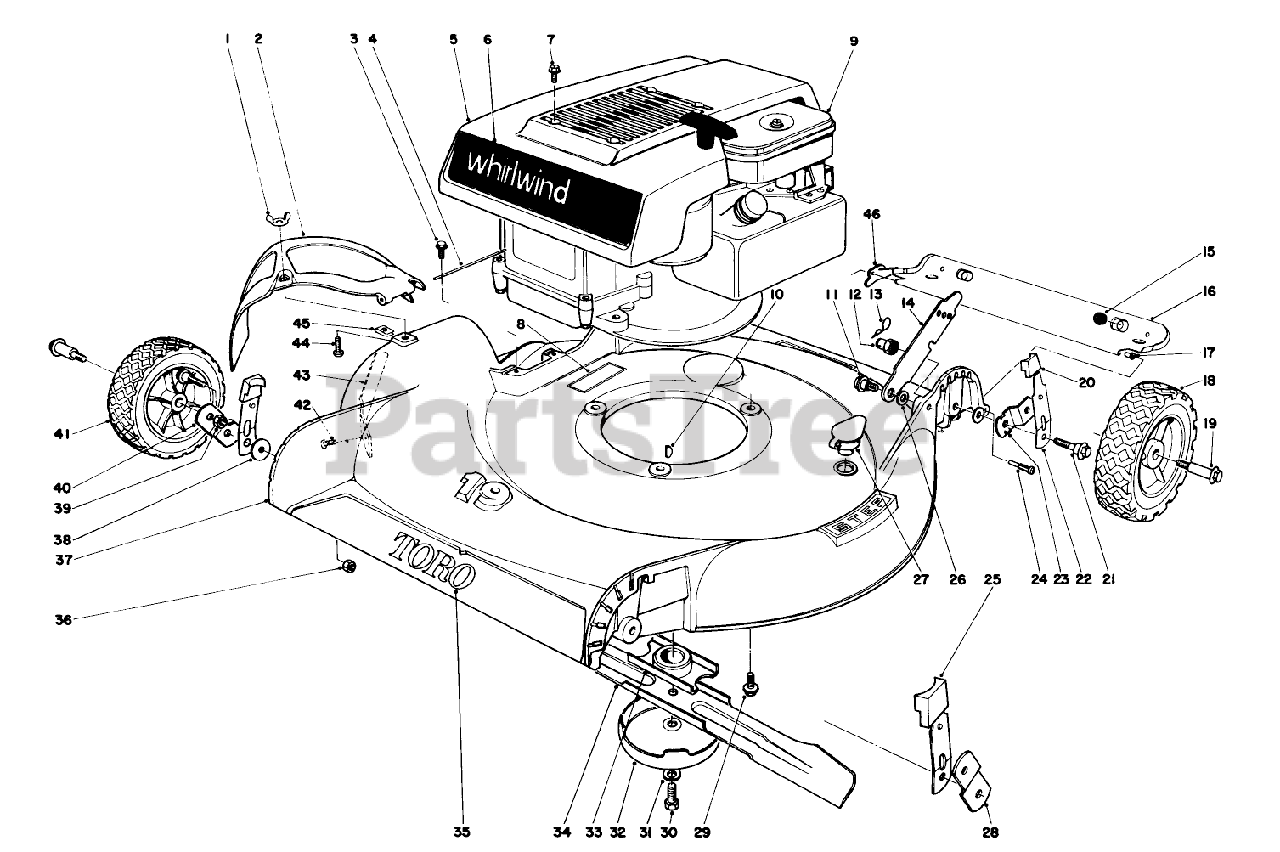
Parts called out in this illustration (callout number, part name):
1	NUT-WING SPECL
3	SCREW
6	Decal Whirlwind
9	Engine (Model 16073)
10	KEY-WOODRUFF
11	SCREW-SHOULDER
12	HANDLE PIVOT NUT
13	PIN-COTTER, HAIR
20	Arm Knob
21	PIVOT SCREW
23	PIVOT ARM PLATED
26	SPACER
27	WASHOUT PLUG
31	WASHER-LOCK
32	Anti Scalp Cup
35	Decal Toro
38	WASHER-PIVOT
40	PIVOT ARM D PLTD
42	Screw
45	NUT-SPEED
